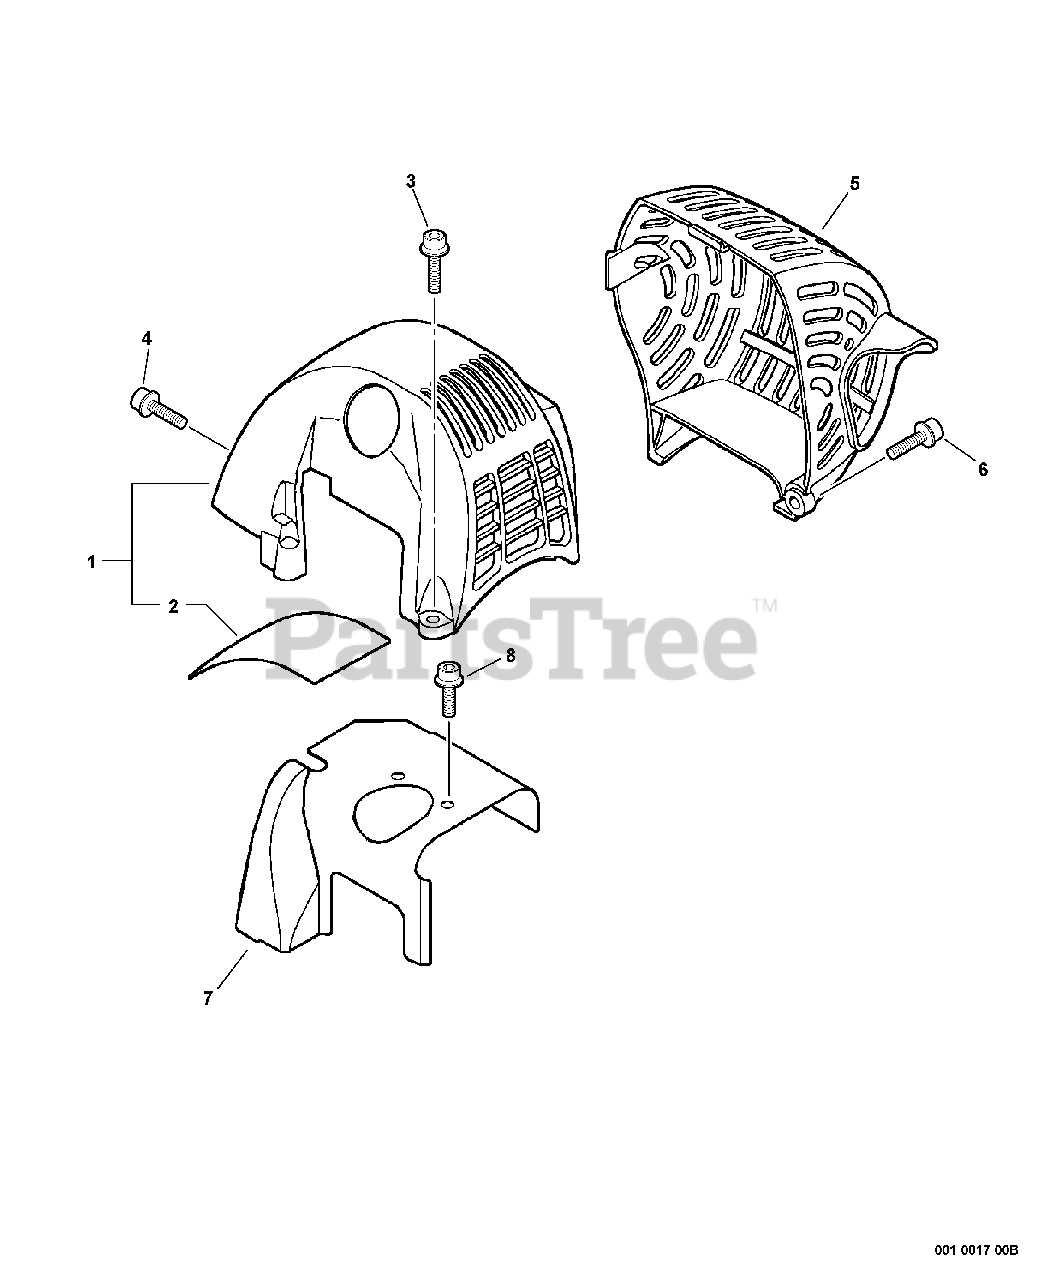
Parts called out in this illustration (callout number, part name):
1	ENGINE COVER ASSY
2	PLATE, INSULATOR
3	SCREW - 5X12
4	SCREW - 4
5	COVER, EXHAUST
6	SCREW - 5X20
7	SHIELD, CYLINDER
8	SCREW - 5X8
